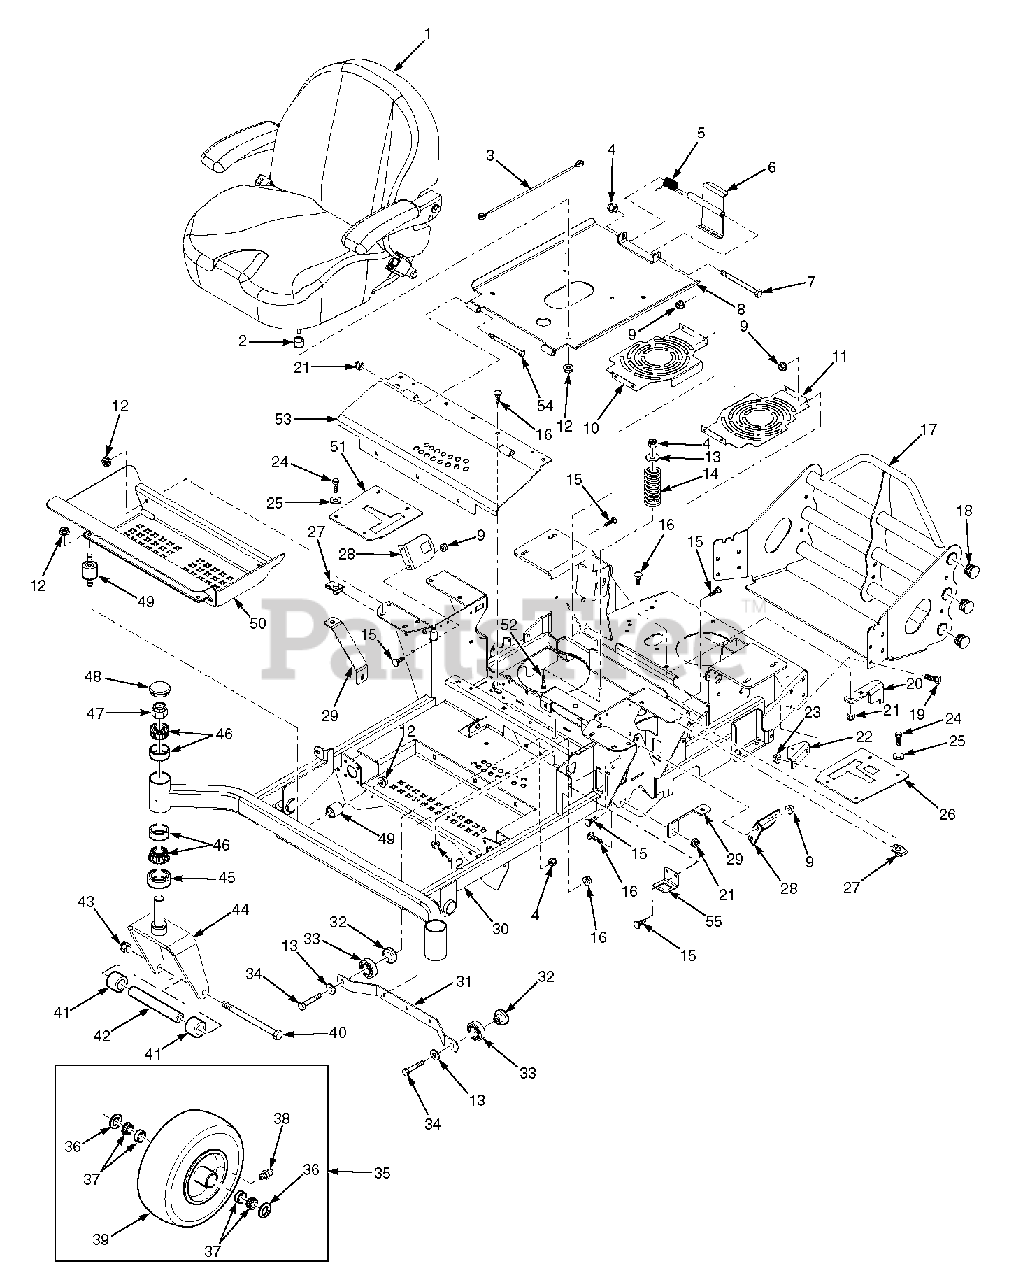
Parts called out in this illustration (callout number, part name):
1	Seat Assembly
2	Spacer
3	Cable, Seat Stop
4	Nut, Elastic Stop 3/8-16
5	Spring, Seat Latch
6	Weldment, Seat Latch
7	Bolt, Hex Head 3/8-16 x 6"
8	Seat Plate Weldment
9	Nut, Serrated Flange 1/4-20
10	Fan Cover, RH
11	Fan Cover, LH
12	Nut, Serrated Flange 5/16-18
13	Flatwasher, 3/8-.391 x .938 x .105
14	Spring, Seat
15	Bolt, Carriage 1/4-20 x 1"
16	Bolt, Carriage 5/16-18 x 3/4"
17	Bumper Weldment
18	Plug, Bumper Tube
19	Bolt, Hex Head 3/8-16 x 1"
20	Anti-Rotation Bracket
21	Nut, Elastic Stop 5/16-18
22	Bracket, Dump Valve
23	Nut, Serrated Flange 3/8-16
24	Bolt, Hex Head 1/4-20 x 1"
25	Flatwasher, 1/4-.312 x .750 x .065
26	Control Plate w/Decal, LH
27	U-Nut, 1/4-20
28	Bracket, Switch Mount
29	Bracket, Tank Mount, SFZ52
29	Bracket, Tank Mount, SFZ61
30	Mainframe Assy., w/Decals - SFZ52
30	Mainframe Assy., w/Decals - SFZ61
31	Support, Deck Guide
32	Spacer, Bearing
33	Bearing
34	Bolt, Hex Head 3/8-16 x 2-1/2"
35	Wheel Assembly
37	Bearing
38	Fitting, Grease
39	Tire, 13 x 5-6
40	Bolt, Hex Head 1/2-13 x 7-1/2"
41	Spacer, Caster Wheel
42	Sleeve, Caster Wheel
43	Nut, Elastic Stop 1/2-13
44	Yoke Weldment
45	Seal, 2" OD x 1.625 ID
46	Bearing Set
47	Nut, Elastic Stop 1"-14
48	Grease Cap
49	Rubber Isolator
50	Footplate Weldment, SFZ52
50	Footplate Weldment, SFZ61
51	Control PLate w/Decal, RH
52	Bolt, Carriage 3/8-16 x 1-1/4"
53	Deck Lift Cover w/Decal, SFZ52
53	Deck Lift Cover w/Decal, SFZ61
54	Bolt, Hex Head 5/16-18 x 3-3/4"
55	Switch Bracket
